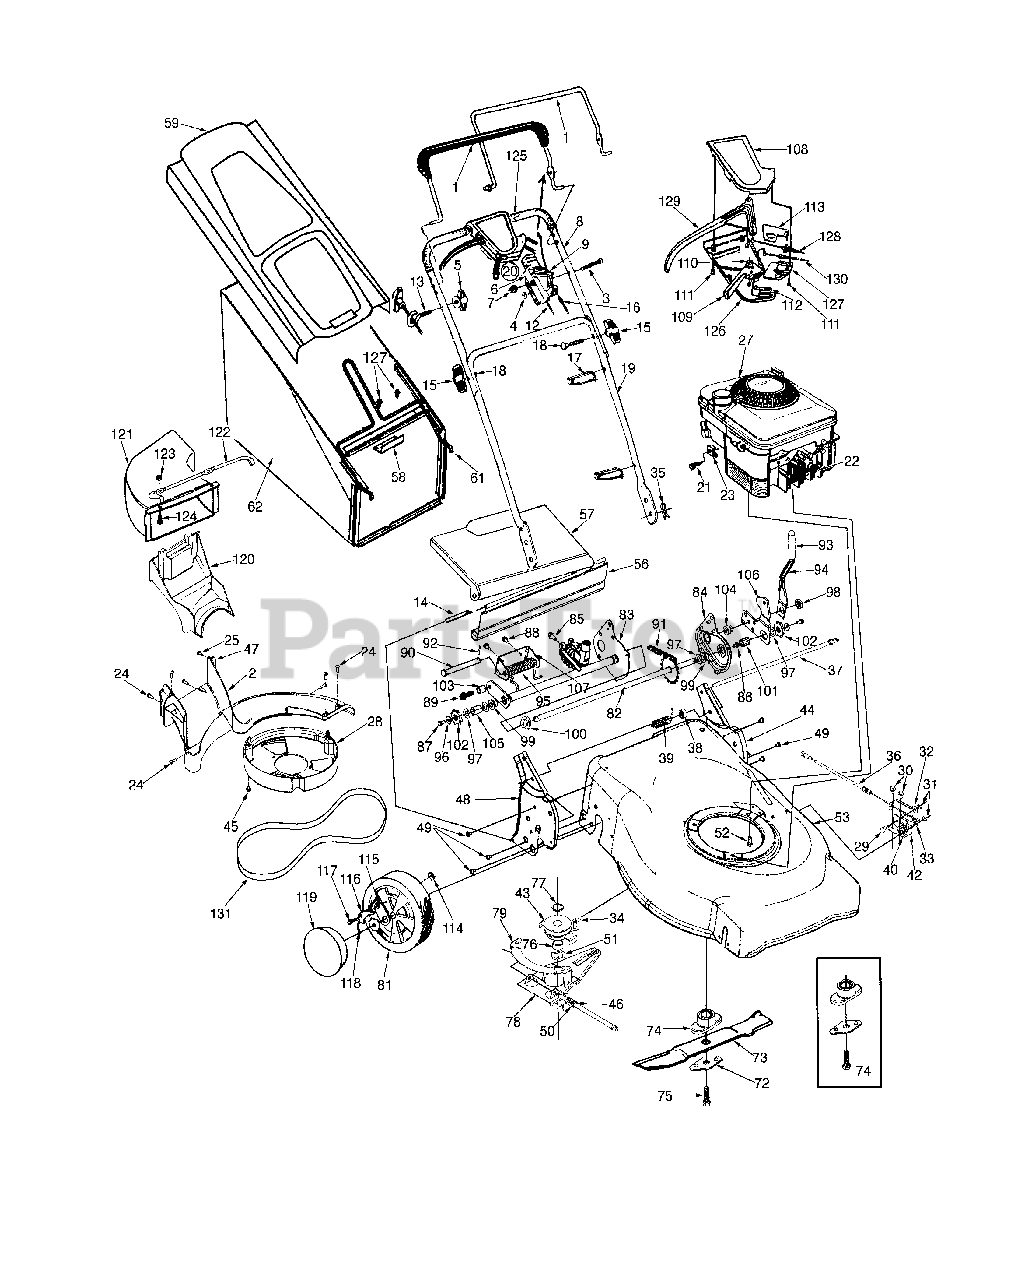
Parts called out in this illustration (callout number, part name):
2	Baffle
3	Oval C-Sunk Mach.-Scr.
4	Spr. Wash..66" I.D.
5	Handle Knob 1/4-20 Thd.
6	Throttle Body
7	Hex L-Nut 1/4-20
9	Throttle Lever
12	Throttle Control Wire-55"
13	Rope Guide
14	Wire-47"Lg.
15	Hand Knob
16	Control Cable-40.5"
17	Cable Tie
18	Curved Hd. Bolt 5/16-18 x 2" Lg.
20	Throttle Box Comp.
21	Hex Self-Tap Scr. #10-32 x .62" Lg. (B&S)
22	Spark Plug Boot
23	Cable Clamp (B&S)
24	Screw H.L. 12-24
25	Screw Mach. B Tapp.
27	Engine
28	Belt Cover
29	Scr. 1/4-20: .50 Lg.
30	Scr.:AB 1/4-20: .625 Lg.
31	Hex Nut: 1/4-20
32	Bell Wash. .265 x .75 x .062
33	Lock Wash. 1/4
34	Shld. Scr. .340 Dia x .350 x 1/4-20
35	Int. Cotter Pin 5/15" Dia.
36	6 Sp. Cable - 53" Lg.
37	Pivot Rod
39	Torsion Spring L.H.
40	Roller Cable
46	Pivot Shaft
47	U-Nut
50	Torsion Spring
51	Wave Washer 1.38 O.D. x .88 I.D x .029
52	Hex L-Wash. Hd. Scr. 3/8-16 x 1" Lg.
62	Grass Bag - Black
72	Blade Bell Support
73	21" Mulching Blade w/Star
74	Blade Adaptor Kit w/Star
75	Hex Bolt 3/8-24 x 2.5 Lg.
76	Spacer - Sleeve
77	Spacer - Sleeve
81	Front Wheel "T" Tread 8" x 1.75"
82	Axle Assy: RR
86	Scr. TT 1/4-20
87	Hx Cap Screw 1/4-20
88	Scr. AB 1/4-20
89	Scr 3/8-16 x 1.25
90	Pin - CIv. .500 Dia. x .4.62 Lg.
91	Chain: Endless 48:.500P x 22L
92	Pin-Cotter .125 O.D. x .75
93	Grip-Foam
94	Spring Lever
95	Torsn Spring
96	Bell Washer .265 x .75 x .062
97	Wash.-Flat .508 I.D. x 1.0 O.D.x .020
98	Nut - Shoulder .625 x .165Lg.
99	Bearing-Fig Hex
100	Bearing-Fig. Hex
101	Bearing-Sleeve
102	Rachet Wheel
103	Spacer - .385 x .625 x .700
104	Spacer-Shoulder .385 I.D. x .715Lg.
105	Spacer Sleeve .520 I.D. x .950 Lg.
106	Pivot Arm
109	6 Speed Shift Lever
110	Gear Insert
111	C-Sunk Tap Scr. #10 x .75" Lg
112	Shift Lever Spring
113	6 Sp. Rack Cable Bracket
114	Weld Top L. 1/4-20
115	Pawl Plate
116	Pawl R.H.
117	Shldr Scr. .340 x .285
118	Spring, Rachet
119	Gray (3-1/2" Dia) Hub Caps
120	Mulch Plug
121	Chute Deflector
122	Chute Mounting Rod
123	Hex-L-Nut 1/4-20 thd.
124	Mach. Scr. 1/4-20
125	Foam Grip
126	Lower Control Housing
127	Cable Mounting Cap
128	S.P. Cable
129	Control Lever
130	6 Speed Cable - 53" Lg.
131	Belt
